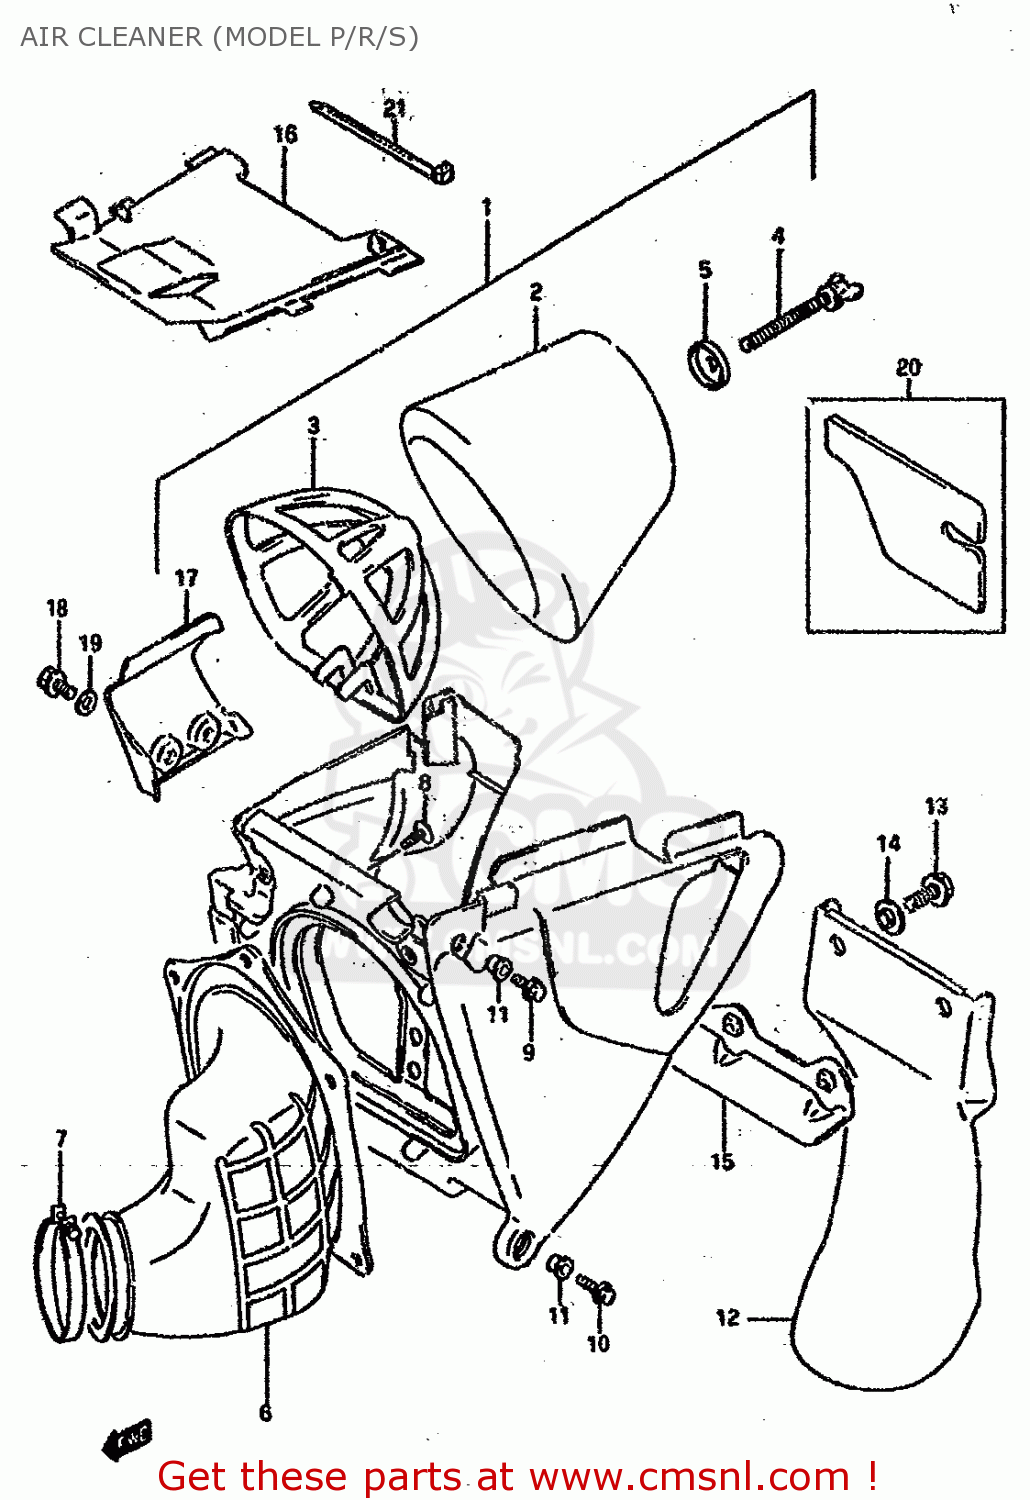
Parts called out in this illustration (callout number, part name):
1	CLEANER ASSEMBLY,AIR
2	FILTER ASSY
3	HOLDER,FILTER
4	BOLT,WING
5	WASHER,AIR CLEANER
6	TUBE,OUTLET
7	CLAMP
8	SCREW
9	BOLT
10	SCREW
11	WASHER
12	GUARD,MUD
13	BOLT
14	WASHER
15	PLATE,MUDGUARD
16	CAP,AIR CLEANER
17	COVER,AIR CLEANER,R NO.2
18	BOLT
19	WASHER
20	GUARD,MUD,UPPER
21	CLAMP(L:129)
